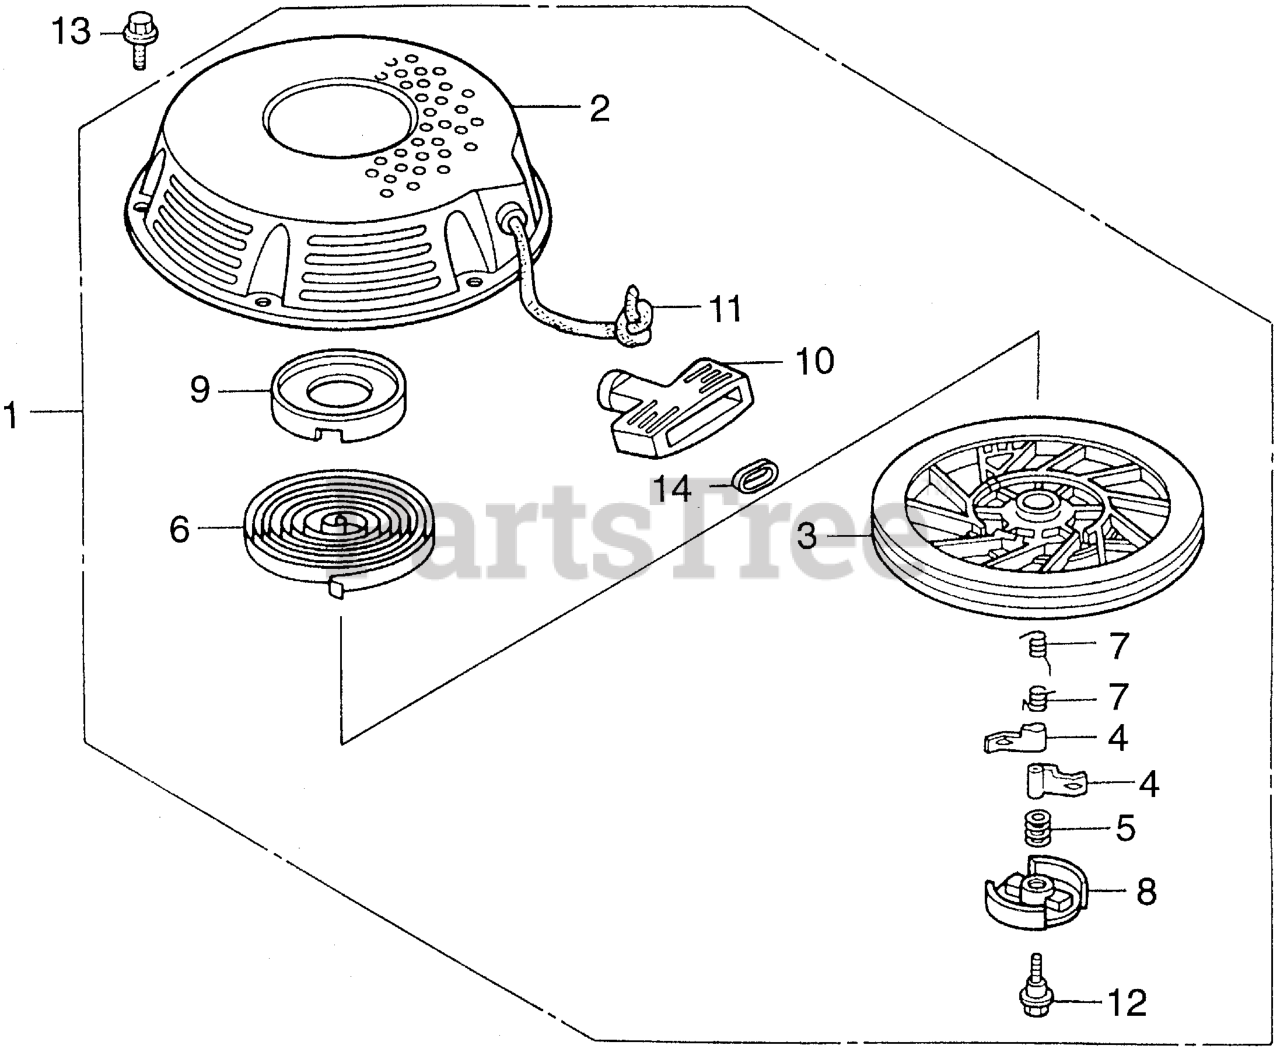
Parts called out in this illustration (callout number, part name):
1	STARTER ASSY., RECOIL *R280* (Honda Code 7660962). (POWER RED)
2	CASE, RECOIL STARTER *R280* (POWER RED)
3	PULLEY, RECOIL STARTER
4	RATCHET, STARTER
5	SPRING, FRICTION
6	SPRING, STARTER RETURN
7	SPRING, RATCHET
8	RETAINER, SPRING
9	HOLDER, SPRING
10	GRIP, STARTER
11	ROPE, RECOIL STARTER (#5X55")
12	SCREW, CENTER
13	BOLT, FLANGE (6X10)
14	GRIP, REINFORCEMENT
